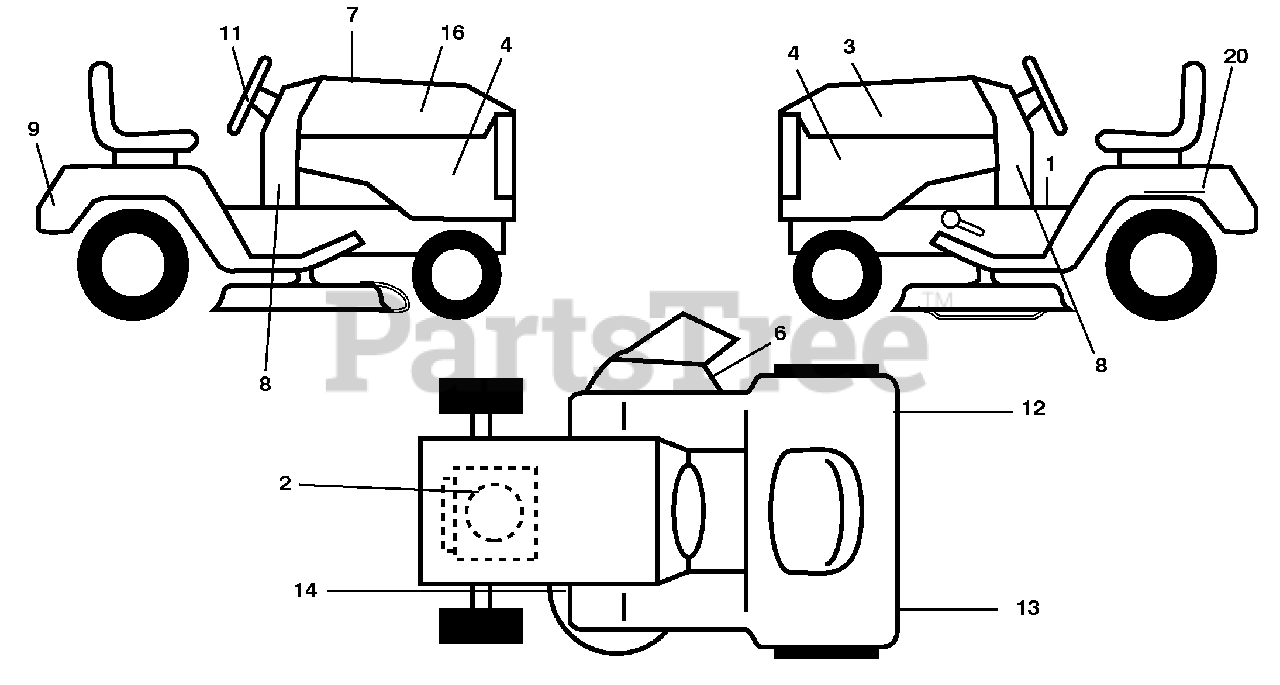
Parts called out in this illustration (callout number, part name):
1	Decal Oper
2	Decal Engine H.P.
3	Decal Hood LH
4	Decal Side Panel
6	Decal Warning, Keep Hand Away
7	Decal Replacement Parts
8	Decal LWRDASH
9	Decal Fender Logo
11	Decal Ins Strg Whl
12	Decal Fender SD RH
13	Decal Fender SD LH
14	Decal V-Belt Schematic
16	Decal Hood Rh
20	Decal Bat Dan/Psn
20	Pad Footrest LH
20	Pad Footrest RH
20	Decal Bypass
20	Manual Operator's E&F
20	Manual Parts
